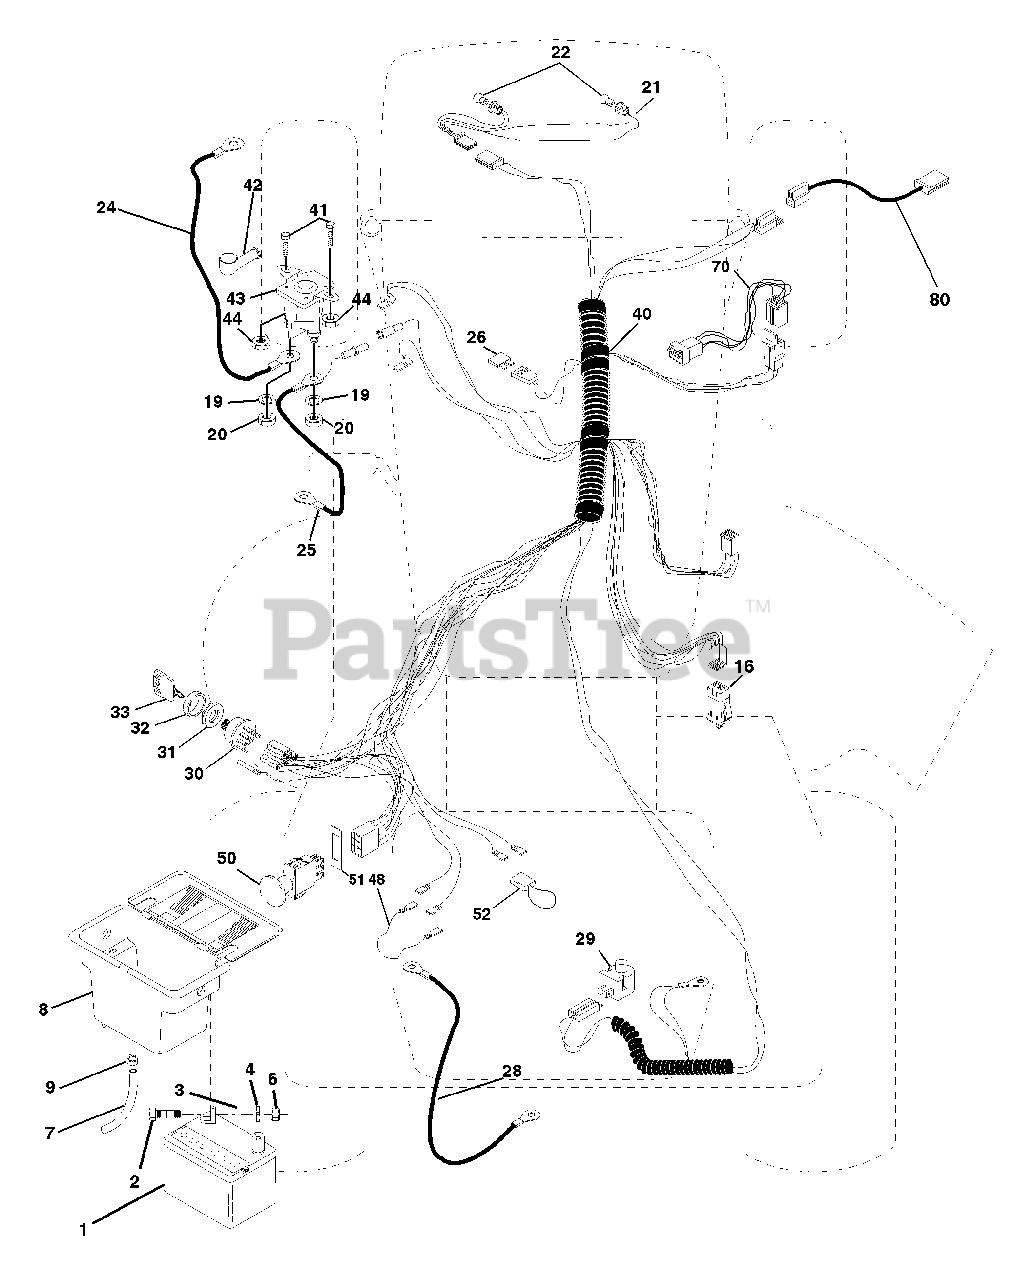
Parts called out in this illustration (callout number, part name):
1	Battery 12 Volt 25 AMP
2	Bolt Hex Hd 1/4-20unc X 3/4
3	Washer 9/32 X 5/8 X 16 Ga.
4	Washer Lock Hvy Helical 1/4
6	Nut Fin Hex 1/4-20 Unc
7	Tube Plastic 12"
8	Case Battery Mech Hinge
9	Clamp Hose Olive
16	Switch Interlock Push-In
19	Washer Lock 1/4
20	Nut Jam Hex 1/4-20 Unc
21	Harness Asm Light W/4152j
22	Bulb Light #1156
24	Cable Battery 6 Ga 11" red
25	Cable Battery 6 Ga 44" red w/16 wire
26	Fuse 30 AMP Auto Green
28	Cable Ground 6 Ga 12" black
29	Switch Plunger Nc Gray
30	Switch Ign 4 pos w/lights
31	Nut Ignition
32	Cover Sw Ignition
33	Key Ign Modelled Generic
40	Harness Ign.
41	Bolt Blk Fin Hex 1/4 - 20 x 1/2
42	Cover Terminal Red
43	Solenoid
44	Nut Keps Hex 1/4-20 Unc
48	Adapter Ammeter Rectangular
50	Switch PTO 3PDT Black Delta 96
51	Ring Retainer PTO
52	Protection Wire Loop
70	Harness, Eng. kohl Cmd-L Dual
80	Harness Clutch EVX
